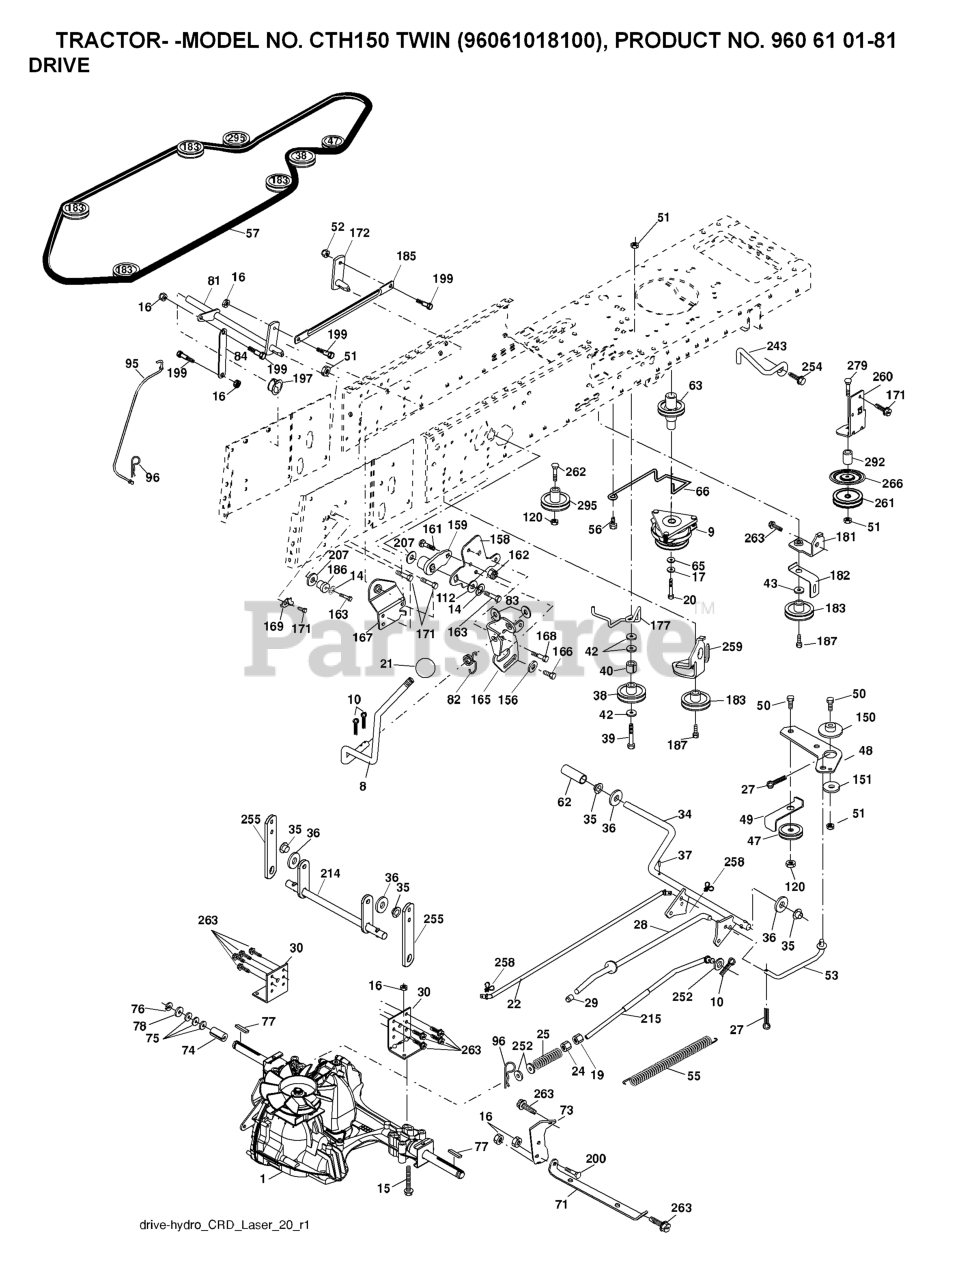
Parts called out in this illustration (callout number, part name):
8	ROD SHIFT FENDER ADJUST LT
9	CLUTCH.ELECTRIC.OGURA.EURO.
10	PIN COTTER
14	LOCKWASHER
15	BOLT HEX 5/16-18 GR 5
16	NUT.71038.31-18.HEX.NYLOCK
19	NUT
20	BOLT HEX 7/16-20X4-1/4"
21	KNOB.DUCKHEAD.1/2
22	ROD
24	NUT
25	SPRING BRAKE ROD
27	COTTER PIN
28	ROD, PARKING BRAKE
29	CAP
30	BRKT, TRNSXLE MNT 20"
34	SHAFT, FOOT PEDAL
35	BEARING.NYLON
37	DRIVE PIN
38	PULLEY.FLAT
42	WASHER
47	IDLER PULLEY
48	BELLCRANK, CLUTCH
49	RETAIN BELT
50	BOLT.3/8-16X1.50
52	LOCKNUT
53	LINK.CLUTCH.7.66.2005
55	SPRING, RETURN LT
56	SCREW.3/8-16
57	V-BELT 113"
62	PEDAL COVER T
63	PULLEY.ENGINE.CVX.LT
65	LOCKWASHER
66	KEEPER BELT ENGINE
71	STRAP TORQUE LH HYDRO
73	STRAP TORQUE RH HYDRO
74	SPACER AXLE
77	SQUARE KEY
81	ASM.CROSS.SHAFT.REAR.CRD.0510
82	SHIFT SPRING
83	WASHER
84	LINK.PNT.TRANSAXLE.0510.CRD
95	LINK
96	RETAINER M
120	NUT LOCK FLG 3/8-16 UNC
150	BUSHING.BELLCRANK.GRD.DR
151	WASHER 12/32X2X10GA
156	WASHER.SRRTD.5/16
158	BRACKET
159	RB HUB.SHIFT
161	BOLT
162	NUT.CROWNLOCK.1/4
165	RP BRACKET
166	CAPSCREW.HXHD.FLG.5/16-18X.625
167	BRACKET.SUPT.SHIFT.CRD
168	BOLT.SHOULDER.5/16-18X
169	PLATE.FASTENING.CROSS.SHAFT
172	LINK
181	BRACKET
182	BELT GUIDE
183	PULLEY.V-IDLER.GRND.DR
185	LINK
186	HUB.TAPERED.ROUND.CRD
187	BOLT.5/16-18X1.25
197	NYLINER SNAP 5/8" ID
199	BOLT SHOULDER 5/16-18 UNC
207	WASHER NYL
214	LEVER
215	ROD
243	BRACKET, ANTI-ROTATION
252	WASHER
254	SCREW 3/8-16X1
255	SHAFT
258	CLIP RETAINER
259	BRACKET
261	FLAT IDLER PULLEY
263	SCREW, 3/8-16X3/4
266	PROTECTOR
292	SPACER
295	PULLEY IDLER COMPOSITE
